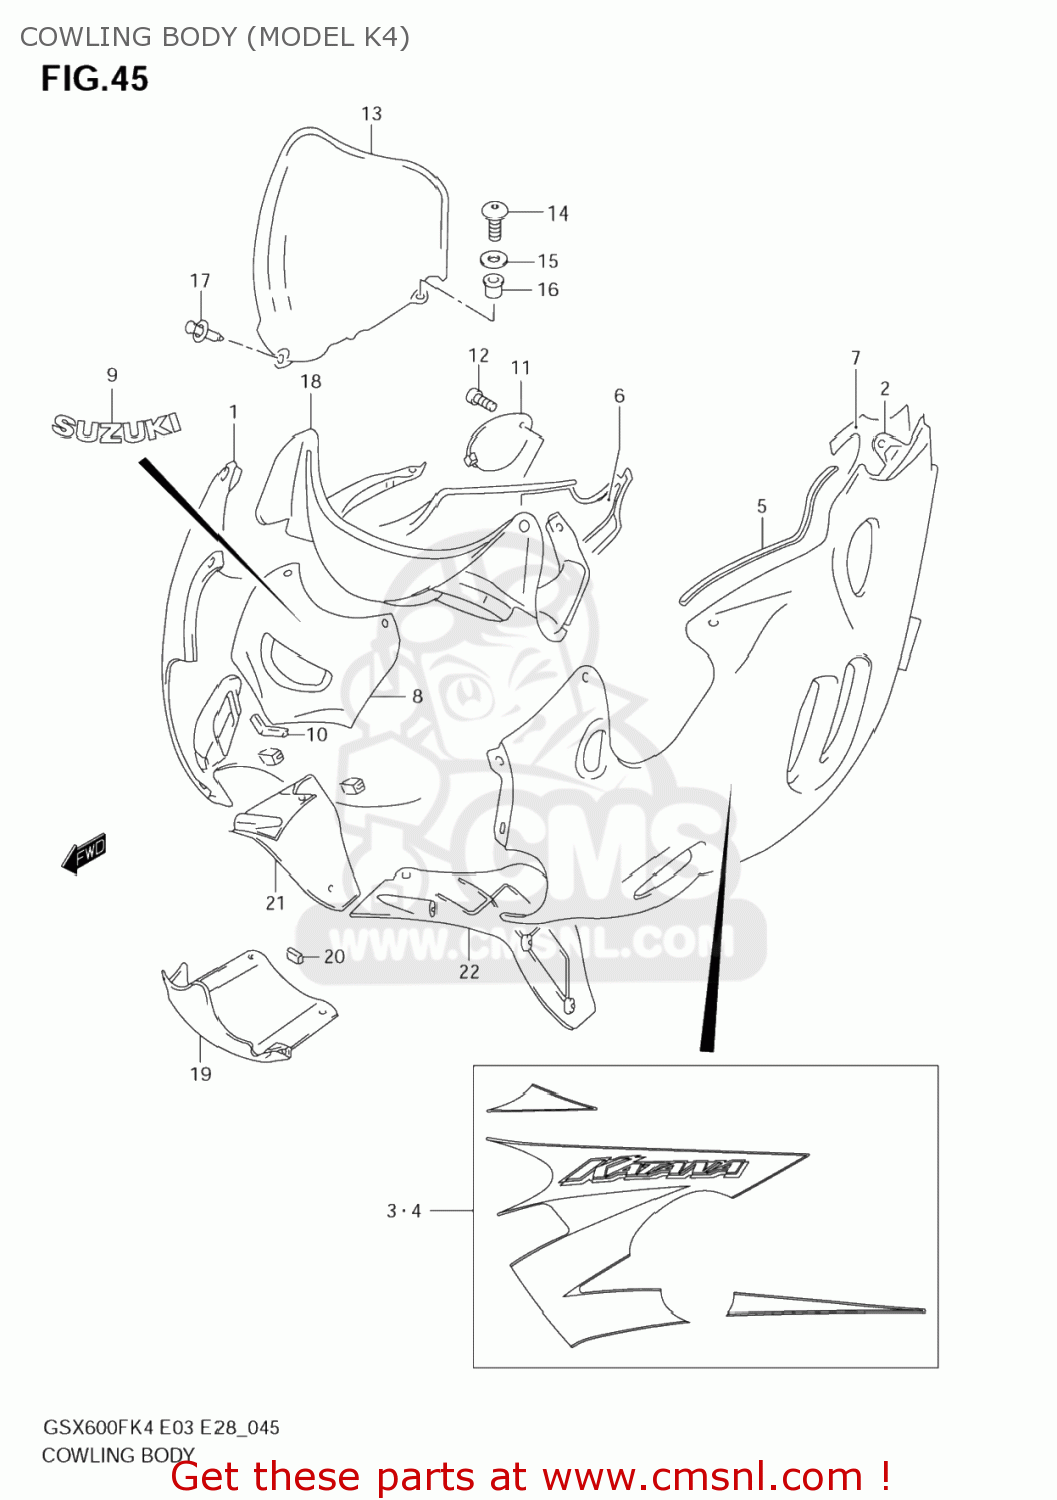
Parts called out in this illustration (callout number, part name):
1	COWLING ASSY,SIDE,R
2	COWLING ASSY,SIDE,L
3	TAPE,COWL SIDE,R(BLUE)
4	TAPE,COWL SIDE,L(BLUE)
5	MOLD,COWLING
6	SHIELD,COWLING COVER,R
7	SHIELD,COWLING COVER,L
8	PANEL,COWLING CTR UPR(BLUE)
9	EMBLEM,FR
10	CUSHION,CTR PANEL UPR
11	LID,OIL
12	SCREW(6X16)
13	WINDSCREEN
14	SCREW(5X14)
15	WASHER
16	NUT
17	CLIP(BLACK)
18	PANEL,METER
19	PANEL,COWLING CTR LWR
20	CUSHION,CENTER PANEL,LOWER
21	PANEL,COWLING INNER,R
22	PANEL,COWLING INNER,L
